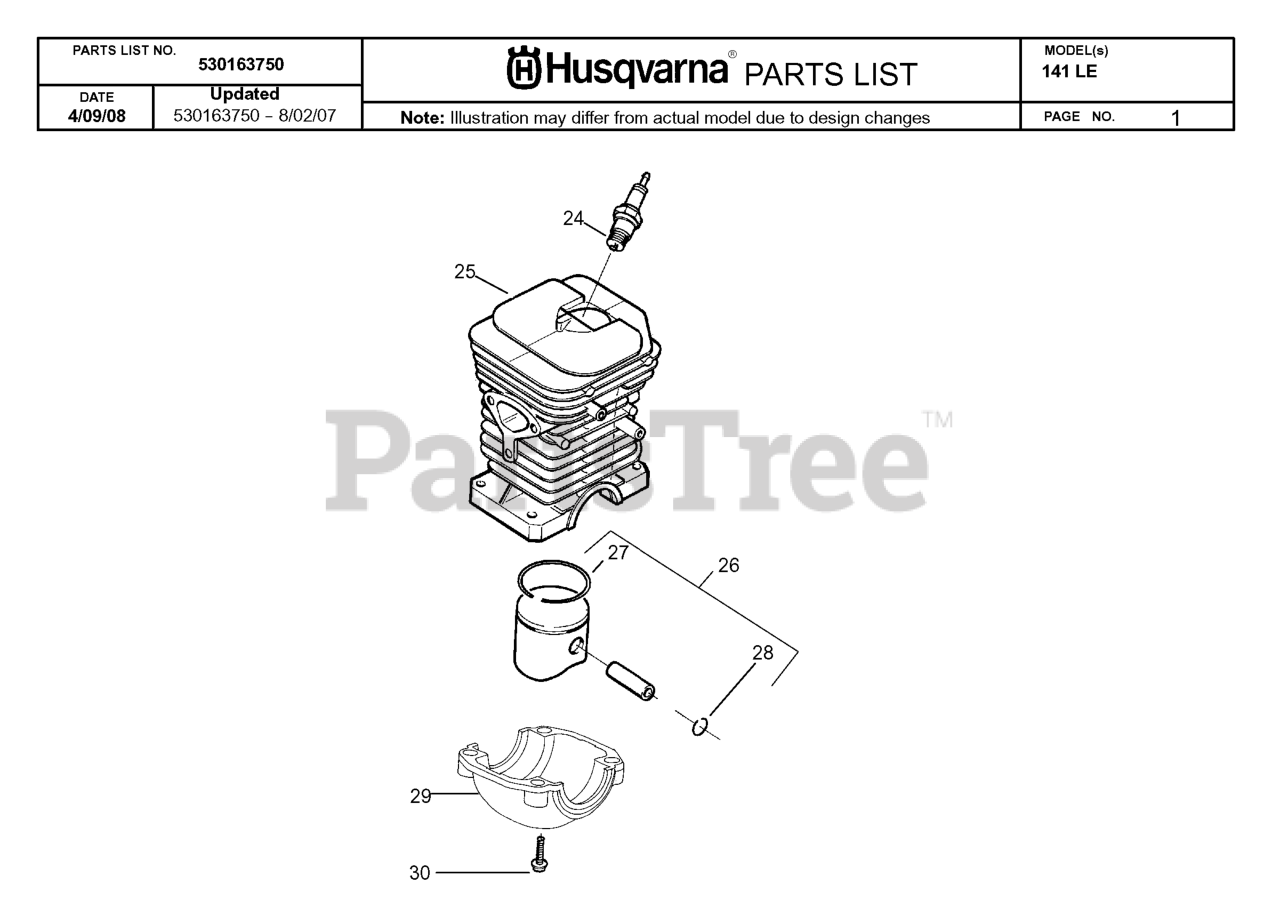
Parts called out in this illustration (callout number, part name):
4	SCREW
5	FRONT LINK ASSY
6	%COMPRESSION SPRING
9	JOURNAL, RIGHT
10	SHAFT PIVOT
11	SPRING,BRK HDL 36/41
13	BRAKE BAND
14	CHAIN BRAKE ASM.
15	SPRING-POSITION
16	CLUTCH COVER
17	ADJUST PIN,BAR 36/41
19	BAR ADJUSTING SCREW
20	CHAIN BRAKE COVER
21	SCREW
23	CYLINDER SHIELD ASSY
24	Spark Plug (RCJ--7Y)
25	CYLINDER ASSY/141
26	KIT-PISTON
27	PISTON RING HV41
28	C-CLIP,PSTN PIN 36/41
29	CAP-CRANKSHAFT
30	SCREW-M5-0.8 X 25MM(TAP)
